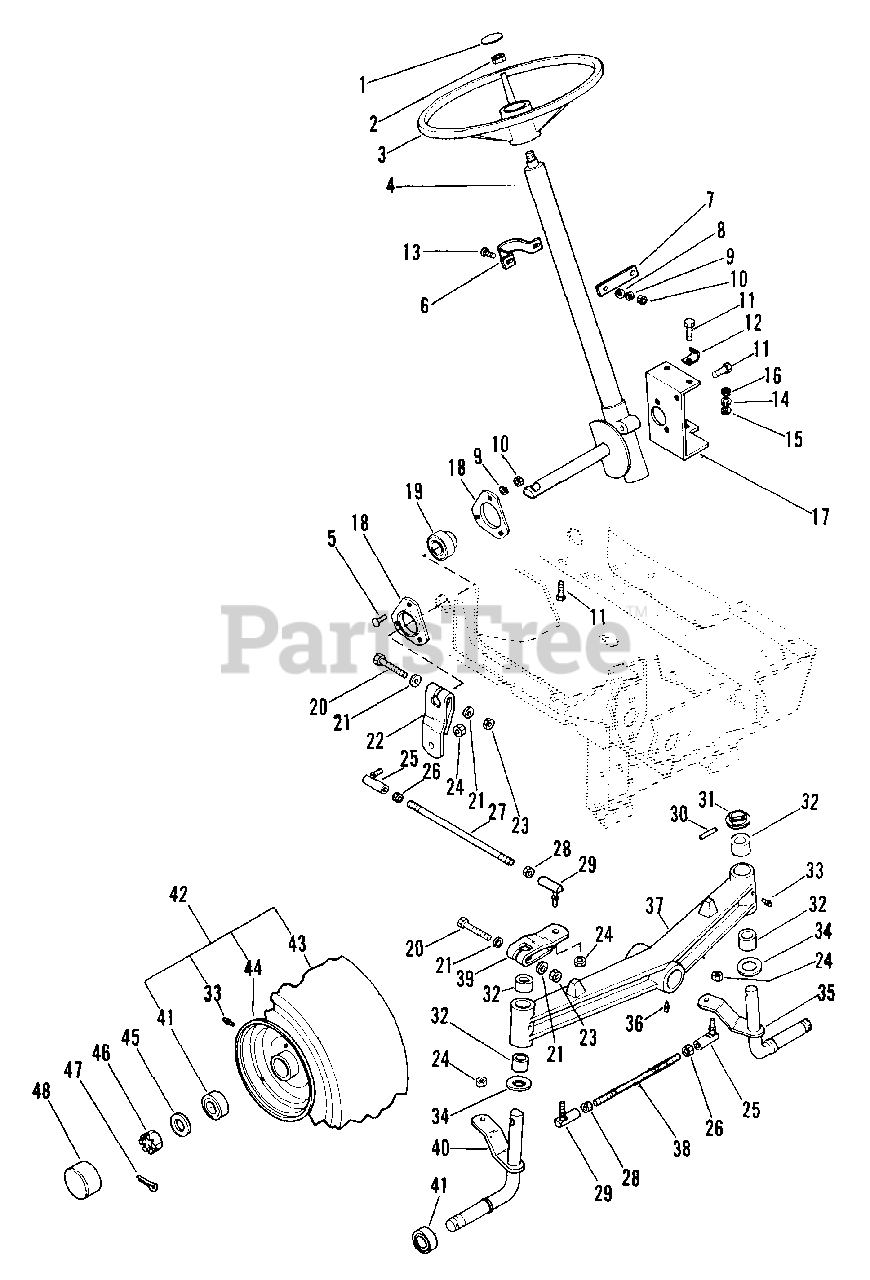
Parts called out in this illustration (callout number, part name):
1	CAP-STEERING WHEEL
2	NUT-LK-JAM .625-18 YWZC
3	STEERING WHEEL
4	STEERING GEAR ASS'Y
5	BLT-RDHDSQNK .31-18X1.00 PL
6	STEERING COLUMN CLAMP
8	WSHR-FL-STL .38X.875X.083 PL
9	WSHR-LK .312X.097 PL HVY
10	NUT-HEX .312-18
11	BLT-HEX .38-16X1.00 PL GR5
12	J-CLAMP
13	BLT-RDHDSQNK .31-18X1.0 SHT PL
14	WSHR-LK .375X.094 MED PL
15	WSHR-FL-STL .438X1.0X.083 PL
16	NUT-LK TOP .375-16 GR C YWZC
17	MOUNTING BRACKET
18	BEARING FLANGE
19	BRG-BALL 1.0X2.047X1.20
20	BLT-HEX .50-13X2.50 PL GR5
21	WSHR-FL-STL .531X.938X.104 PL
22	STEERING ARM
23	NUT-LK-CROWN .50-13 GR C PL
24	NUT-LK .50-20 PL
25	BALL JOINT L.H.
26	NUT-JAM .50-20 LH THD PL
27	DRAG LINK
28	NUT-JAM .50-20 PL
29	BALL JOINT R.H.
30	PIN-ROLL .250X1.75
31	SPINDLE CAP
32	BSHG-SLV 1.000X1.125X.875
33	SPIN DRIVE ZERK FITTING
34	PLASTIC WASHER
35	L.H. SPINDLE
35	SPINDLE LH
36	ZERK FITTING
37	FRT AXLE
37	FRONT AXLE ASSY
38	TIE ROD
39	FRONT STEERING ARM
40	R.H. SPINDLE
40	SPINDLE RH
41	BRG-BALL 1.0X2.0X.55
42	T/WHL ASSY
43	TIRE 16X6.50-8 2 PLY
45	WSHR-FL-STL 1.015X1.500X.125
46	NUT-SL 1.0-14
47	PIN-COTR .18X1.25 PL
48	FRONT HUB CAP
